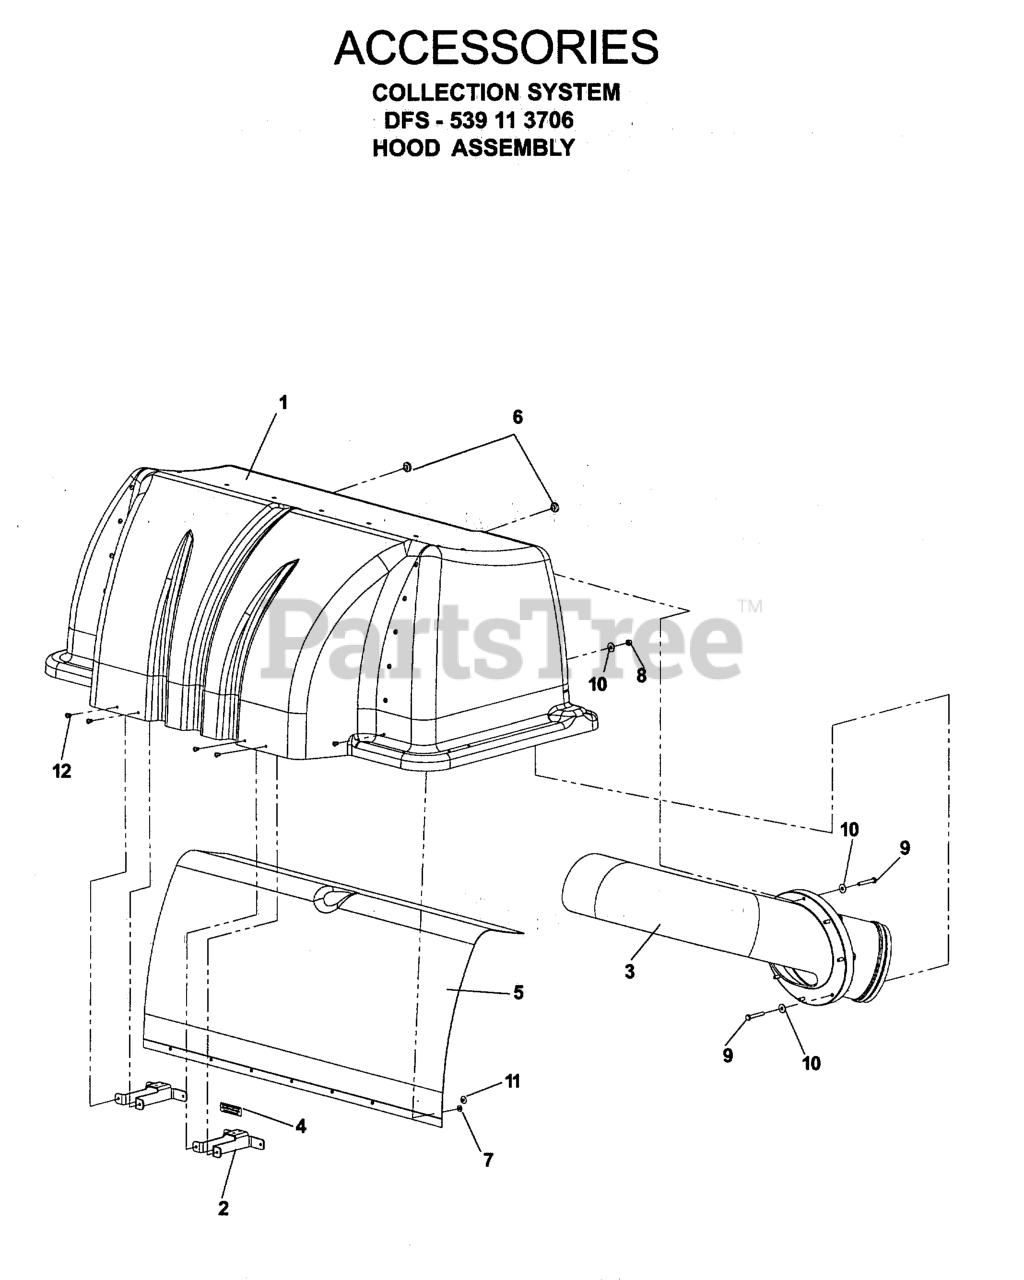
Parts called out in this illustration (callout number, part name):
2	SUPPORT, DRAW LATCH
4	DECAL, VENTILATION
5	MESH, POLY DIAMOND
6	GROMMET, BUMPER
7	WASHER #10
8	NUT.1/4-20.HEX.NYLOC.ZD
9	BOLT 1/4C X 1 3/4
10	WASHER 1/4 FLAT
11	RIVET E/16 X 1/4 LG FLG
12	RIVERT, 3/16, STAVEX
